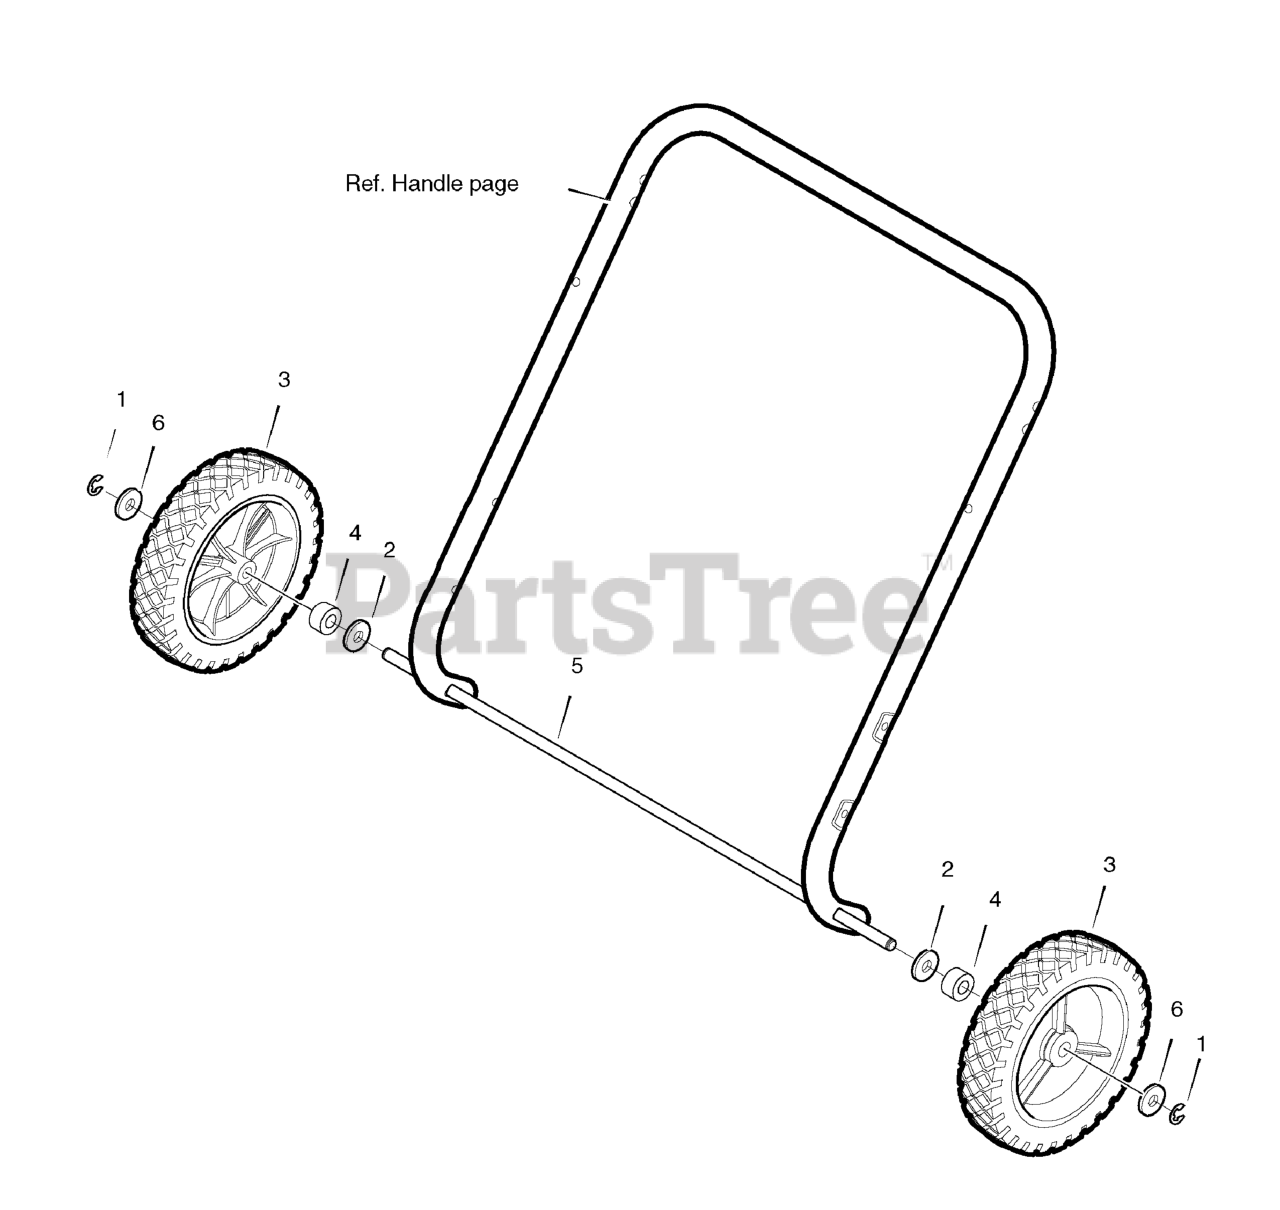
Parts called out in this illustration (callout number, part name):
1	RETAINER, E-Ring
2	WASHER
3	WHEEL & TIRE, 7" x 1-1/2"
4	SLEEVE, Spacer
5	ROD, Axle
